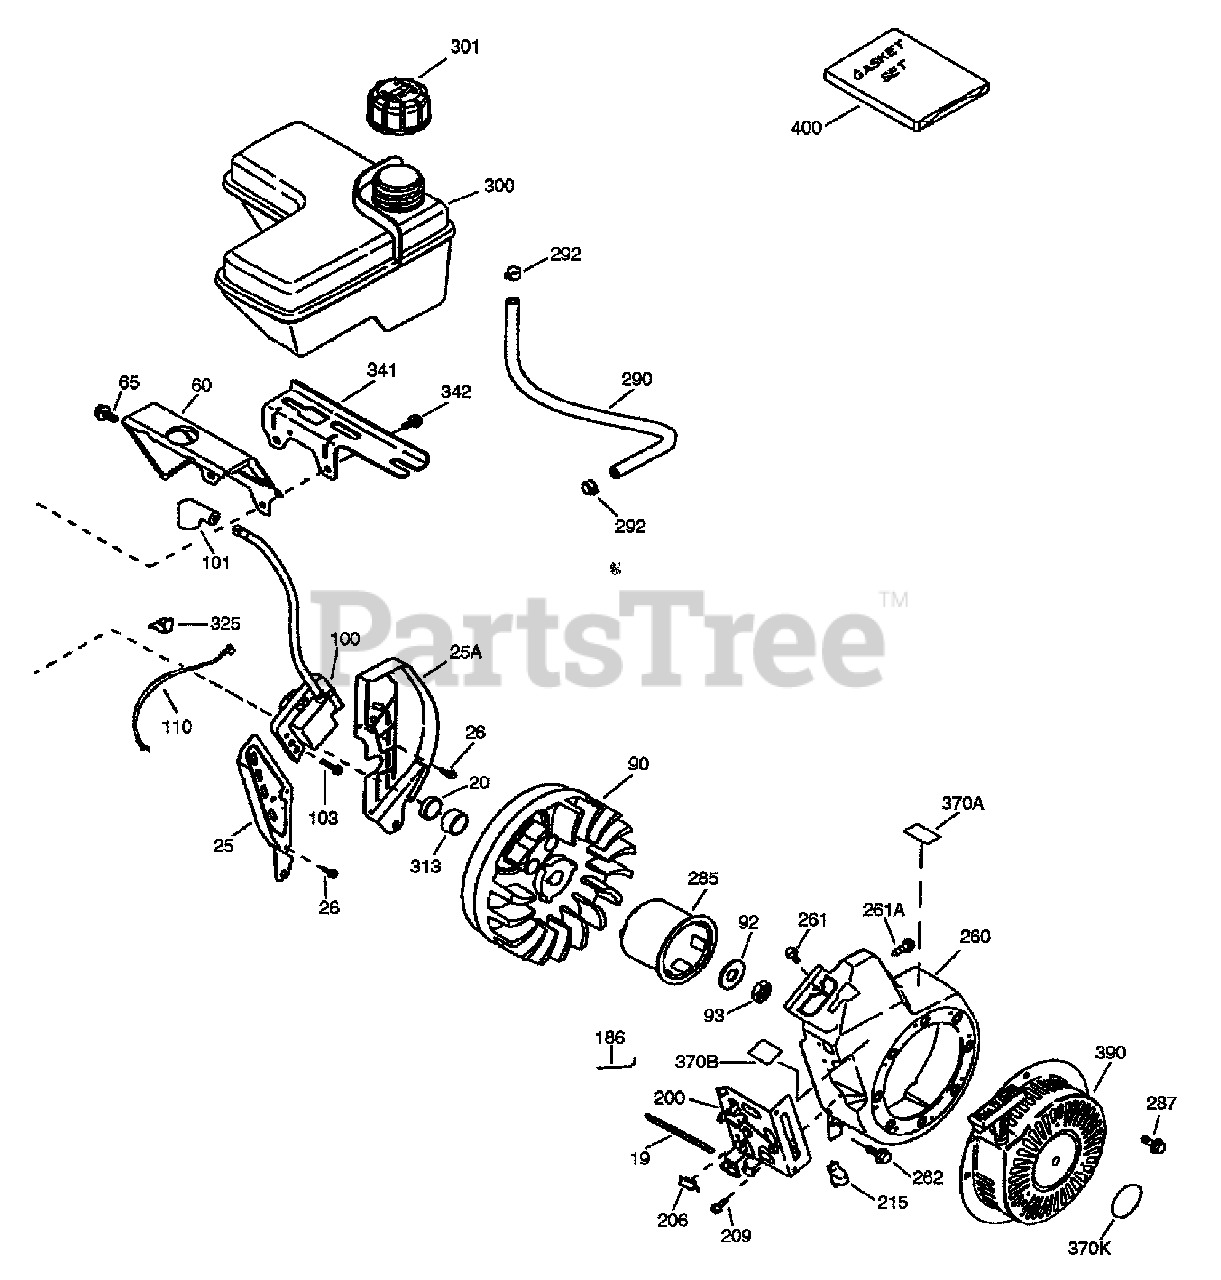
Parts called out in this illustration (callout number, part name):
19	Extension Spring
25	Air Baffle
25A	Air Baffle
26	Screw, 10-24 x 9/16"
60	Blower Housing Extension
65	Screw, 10-24 x 9/16"
92	Belleville Washer
93	Flywheel Nut
100	Solid State Ignition
101	Spark Plug Cover
103	Screw, Torx T-15, 10-24 x 15/16"
110	Ground Wire
186	Governor Link
200	Control Bracket
209	Screw, 10-32 x 1/2"
215	Control Knob
260	Blower Housing
261	Screw, 1/4-20 x 31/64"
261A	Screw, 10-32 x 1/2"
262	Screw, 1/4-20 X 31/64"
285	Starter Cup
287	Screw, 1/4-20 x 31/64"
290	Fuel Line
292	Fuel Line Clamp
300	Fuel Tank
301	Fuel Cap
325	Wire Clip
341	Fuel Tank Bracket
342	Screw, 1/4-20 x 7/8"
370A	Lubrication Decal
370B	Speed Control Decal
370K	Starter Decal
390	Rewind Starter
400	Gasket Set
